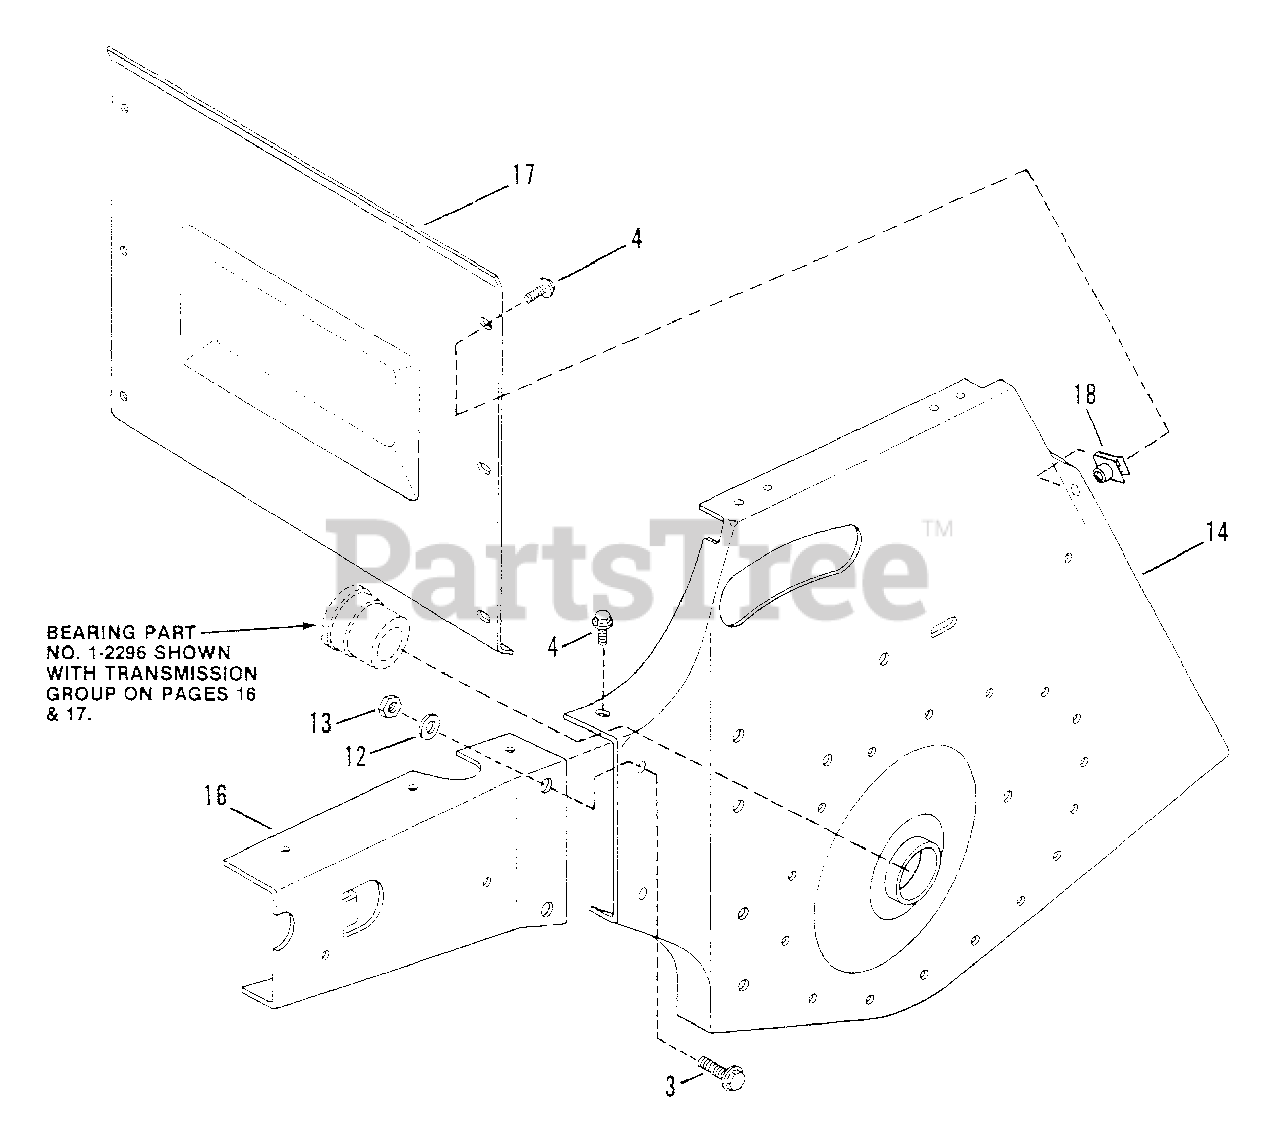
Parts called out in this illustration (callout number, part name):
3	BOLT, 3/8-16 x 1" Hex Flange Lock
4	SCREW, 5/16-18 x 5/8" self-Tapping
12	WASHER, 318 Flat
13	NUT, 3/8-16 Hex Center Lock
14	SUPPORT, Transmission (Left Hand)
16	EXTENSION, Transmission Support (Left Hand)
17	COVER, Rear
18	NUT, 5/16 Push On
